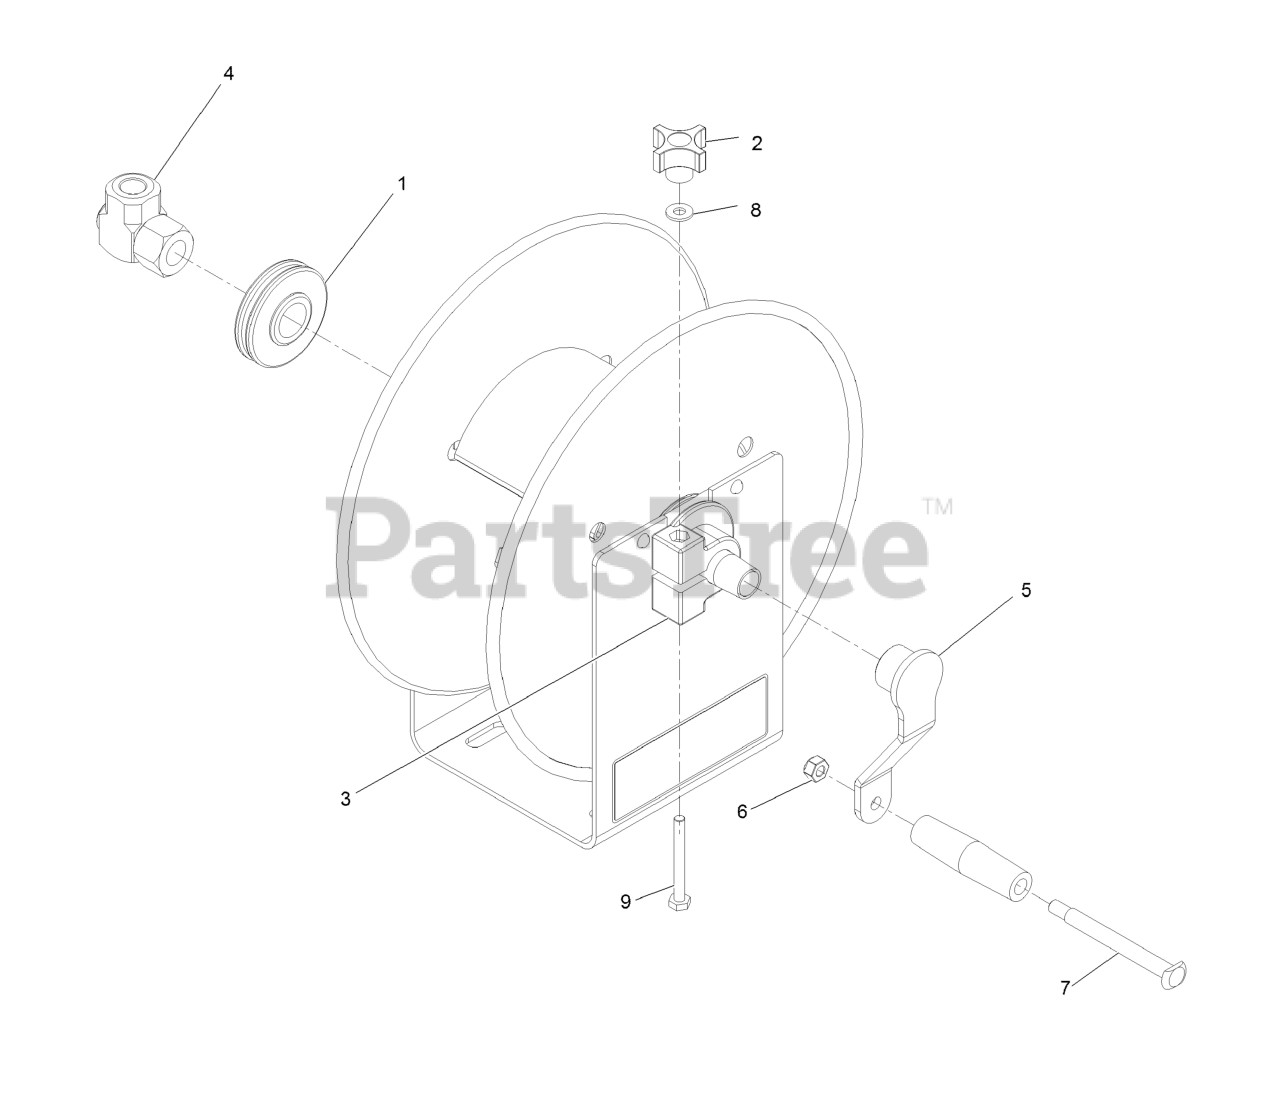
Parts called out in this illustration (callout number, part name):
1	PLASTIC BEARING
2	HOSE REEL BRAKE KNOB
3	BRAKE/BEARING 6329-1-1
4	SWIVEL 3/8" NPT
5	Crank-Reel
6	NUT-HEX
7	BOLT, HOSE REEL HANDLE
8	Washer-Flat
9	SCREW-HH
